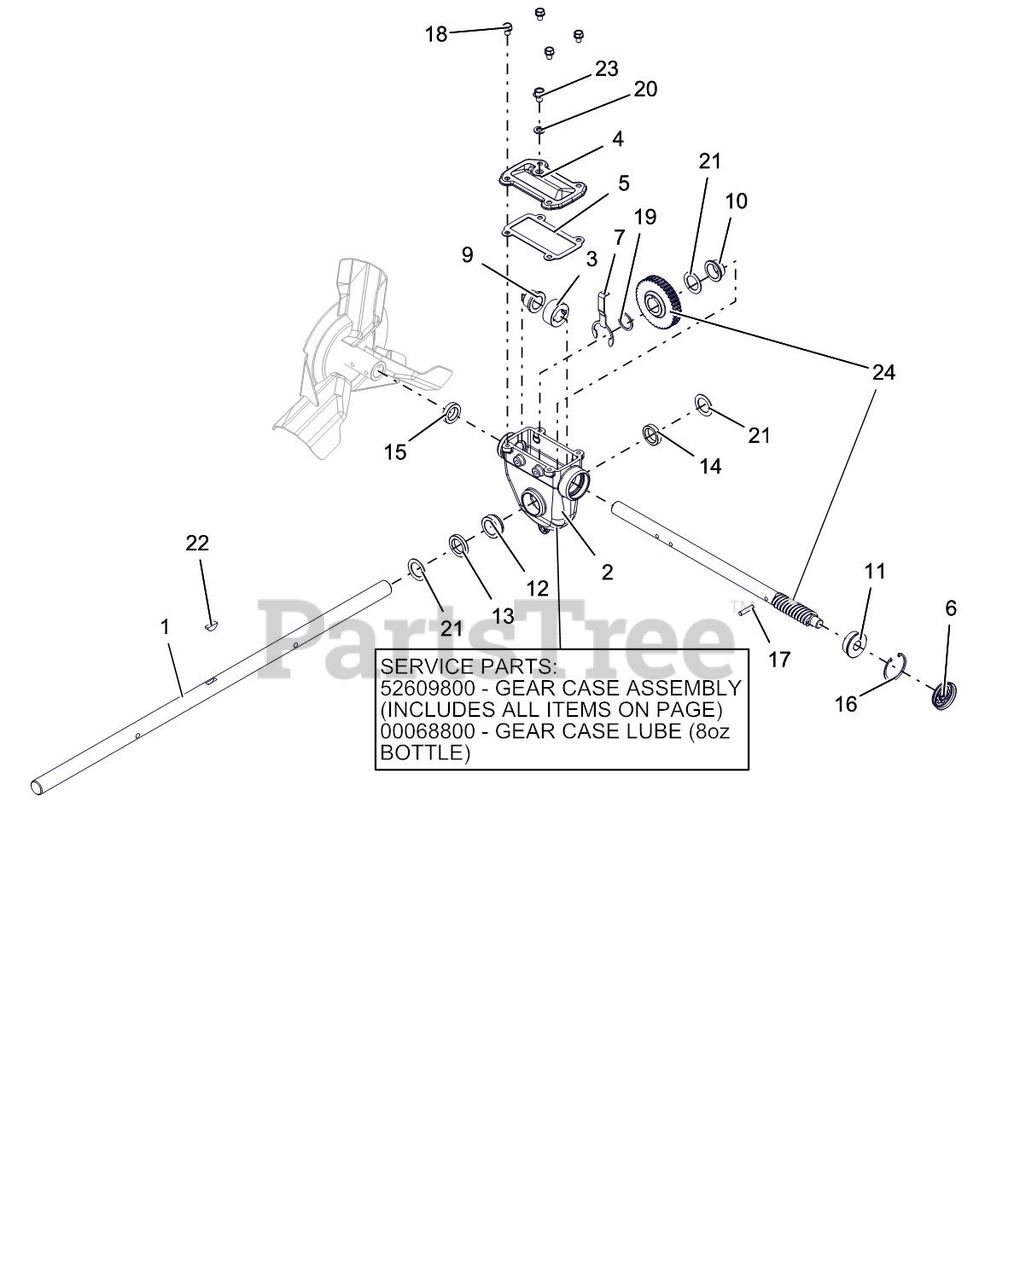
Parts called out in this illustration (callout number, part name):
1	SHAFT, RAKE-32"
2	ARIENS L3 LUBE, 8 OZ BOTTLE
2	GEARCASE, LARGE MACHINED
2	GEAR CASE, 32" IRON PRO TOP-LD
3	THRUST COLLAR, .875"ID SLIPFIT
4	COVER, TOP - LARGE IRON
5	GASKET, TOP - LARGE GEARCASE
6	COVER, GEAR CASE 1.75"
7	BUSHING RETAINER, LARGE
9	BSHG-FLG .879X1.128X.75X1.45
10	BSHG-FLG 1.006X1.128X.555X1.45
11	BSHG-FLG .628X1.503X.58X1.725
12	BSHG-FLG LARGE, RIGHT
13	SEAL-OIL .999X1.500X.250 TBC29
14	SEAL-OIL .999X1.375X.312 TBC29
15	SEAL-OIL .873X1.375X.312 TBC29
16	RG-RTNG-INT 1.750X.062
17	PIN-STR .250X1.12 6150
18	BOLT, SEMS .31-18X.50 GR5 YWZC
19	WSHR-FL-STL 1.010X1.250X.068YZ
20	WSHR-BND-SEAL .38X.75X.11 GALV
21	WSHR-FL-STL 1.010X1.505X.062YZ
22	KEY-WDRF .25X.875 HRD #A
23	@SCR-ROLOK .38-16X.50 HWH YWZC
24	ASSY, WORM SHAFT & GEAR
